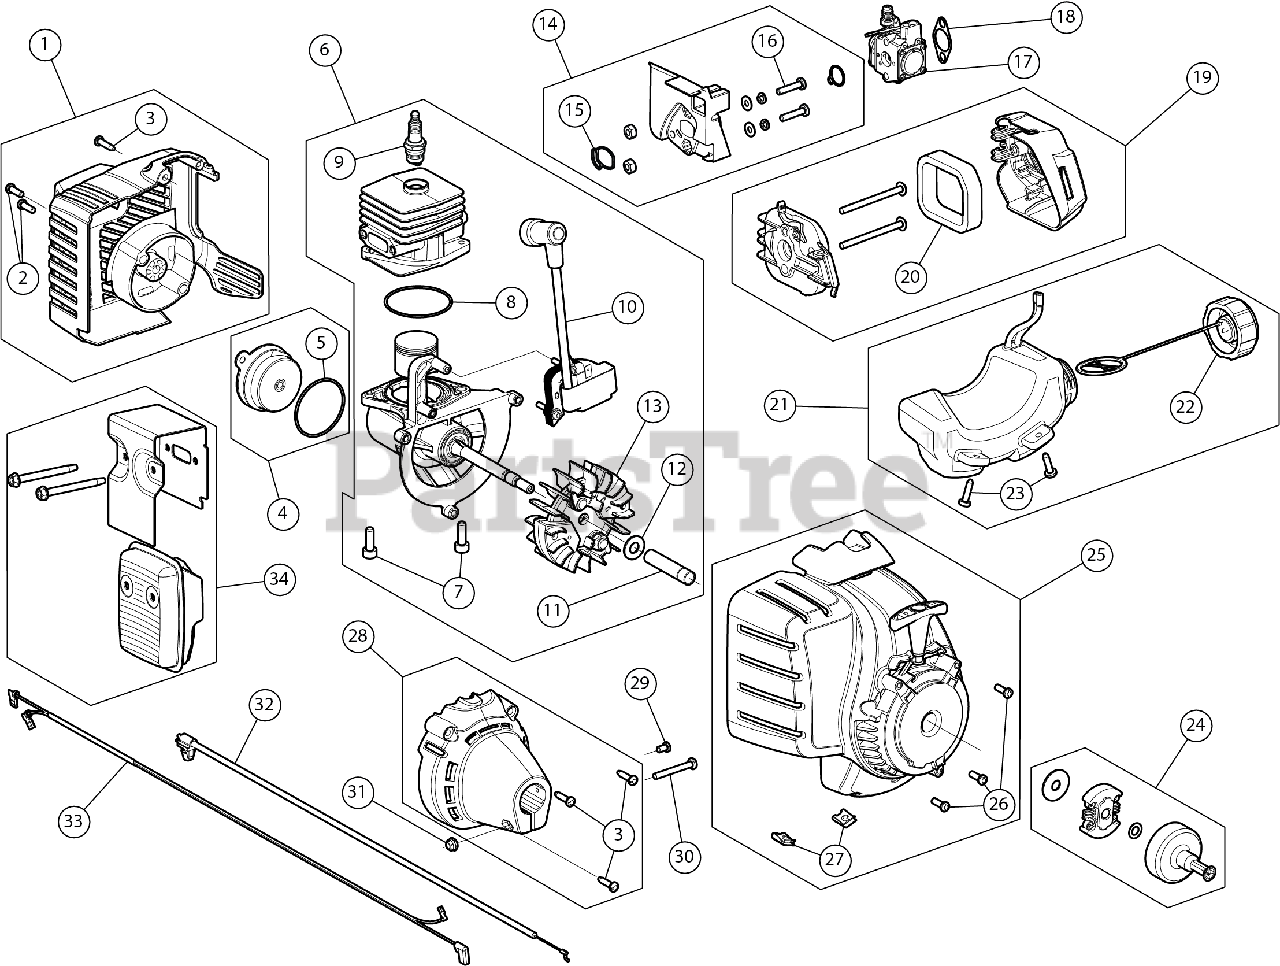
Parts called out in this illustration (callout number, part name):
1	REAR ENG CVR
3	SCREW, #8-16X.750 PH
4	ELECTRIC START COVER
6	SHORT BLOCK
7	SCREW, 1/4-20 x .75
9	SPARK PLUG 14MM
10	MODULE W/SLV RFI
12	BELL WASHER
13	FLYWHEEL ASSEMBLY
14	INTAKE ASSEMBLY
17	CARBURETOR
18	GASKET CARB
19	AIR CLEANER ASSEMBLY
20	AIR FLITER
21	FUEL TANK ASSEMBLY
22	FUEL CAP ASSEMBLY
23	SCREW:10-6 x .75
24	SMALL CLUTCH ASSEMBLY W/SMALL DRUM
25	STARTER HOUSING RED INT
26	SCREW:10-32X.562:#8P
27	NUT, TINNERMAN U-T
28	CLUTCH COVER
29	SCREW, 8-32 x .312 P
30	SCREW
32	THROTTLE CABLE
33	WIRE LEAD W/SUPPR
34	MUFFLER ASSEMBLY
